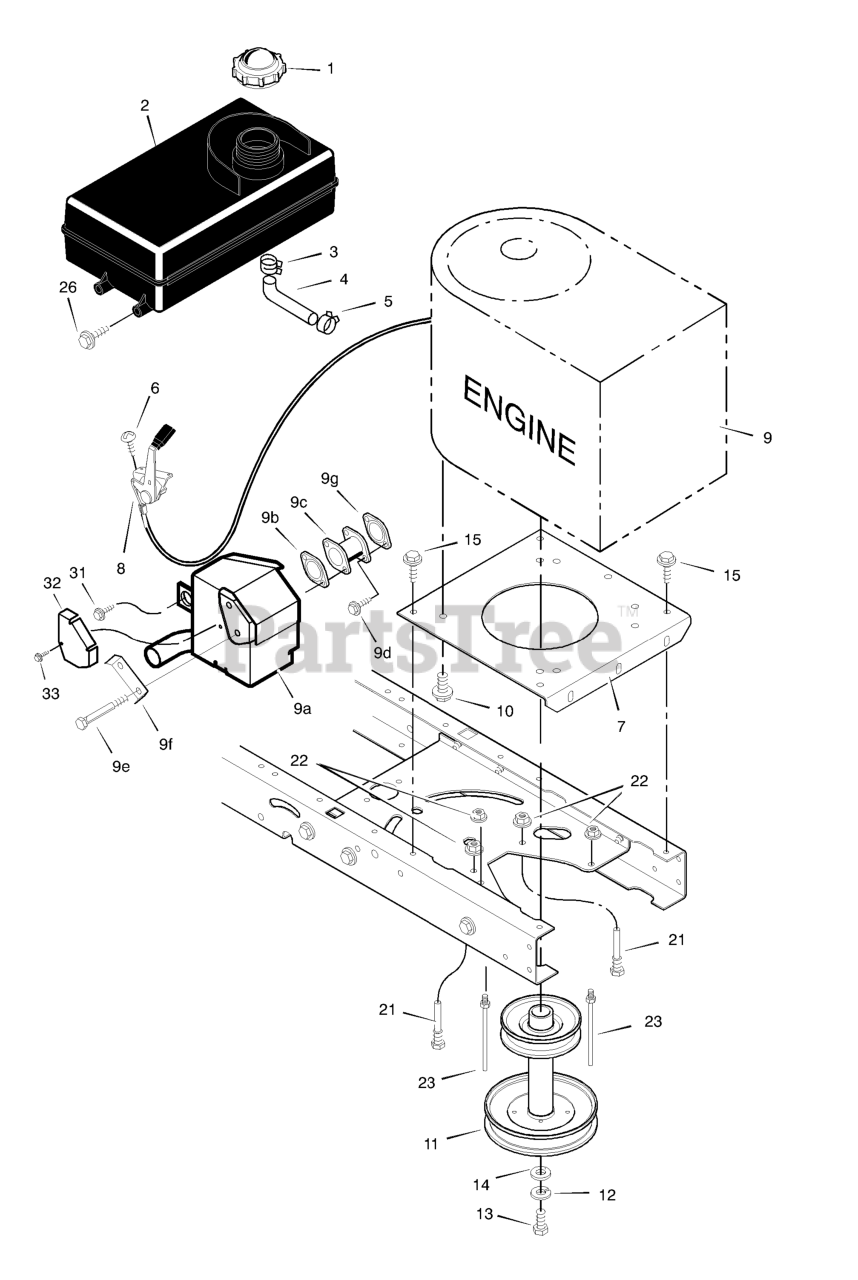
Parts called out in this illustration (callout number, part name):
1	Fuel Cap
2	TANK, Fuel 1.4 Gal.
3	Hose Clamp
4	Fuel Line (Must cut to length)
5	Hose Clamp
7	Plate, Engine
8	Throttle Control
9	Engine
9A	Muffler and Heat Shield
9B	GASKET, Exhaust
9C	Adapter, Muffler
9D	Screw, Adapter
9E	Bolt, Muffler
9F	Lock, Screw
9G	Gasket, Muffler
10	Bolt, Engine Mount
11	STACK PULLEY ASSEMBLY
12	Lockwasher
13	Bolt, Hex
21	Guide, Belt
22	Nut, Flange
23	Guide, Belt
32	Shield, Heat
